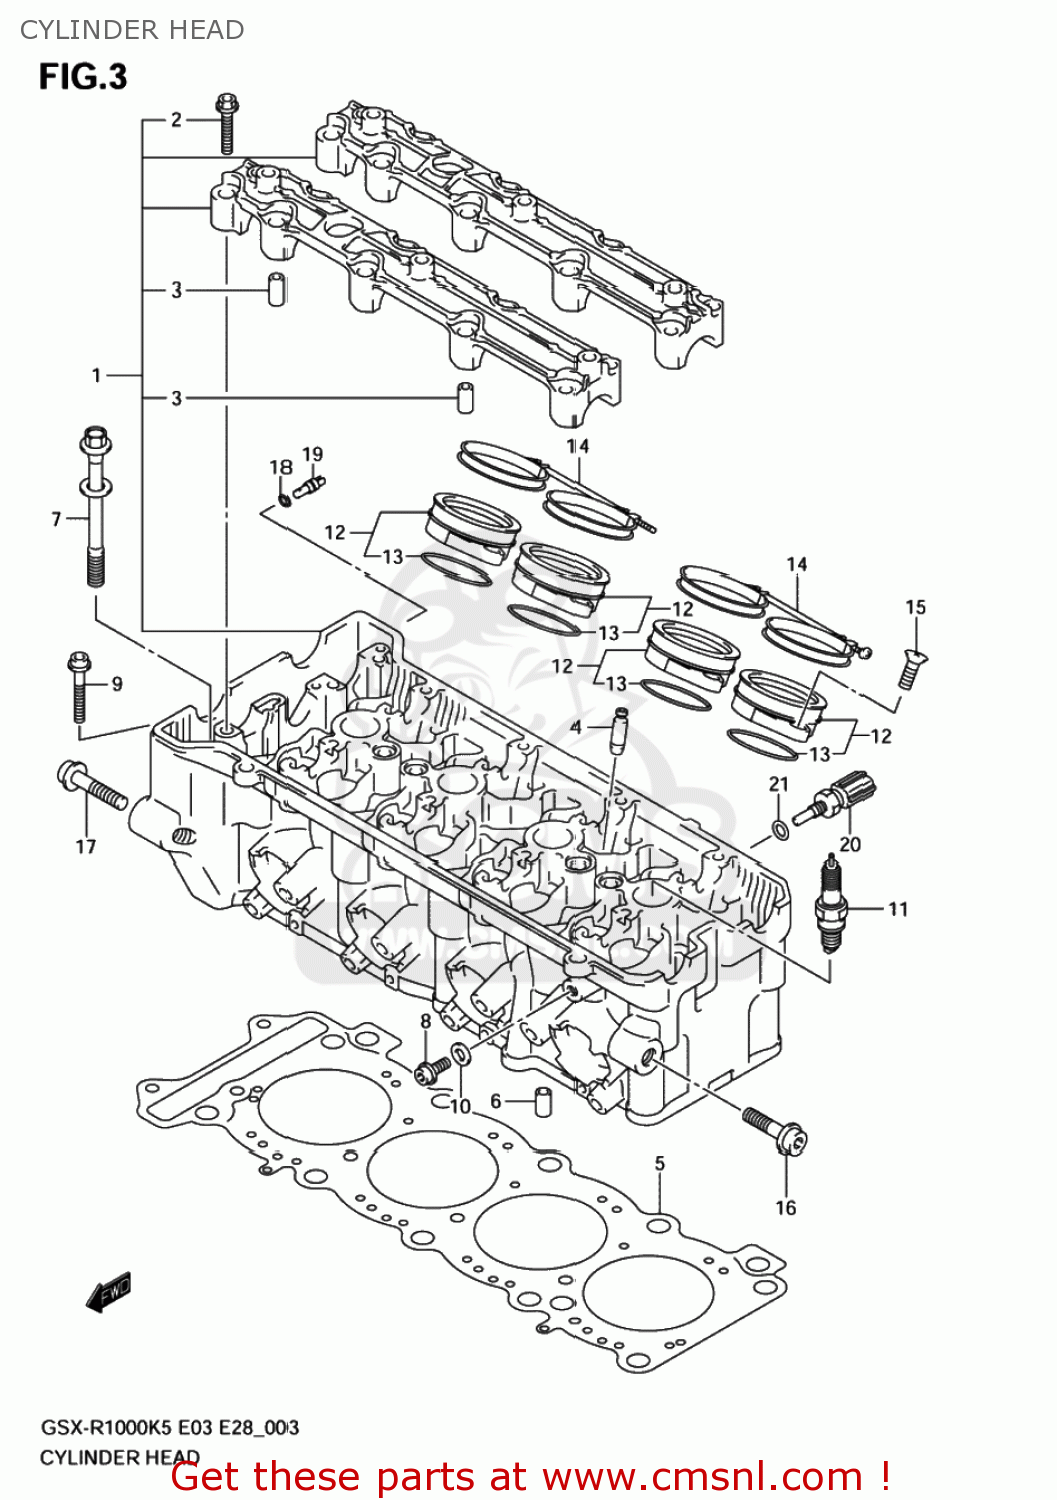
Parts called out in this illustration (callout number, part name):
1	HEAD ASSY,CYLINDER
2	BOLT(6X40)
3	PIN(6.2X8X16)
4	GUIDE,VALVE(OS:0.3)
5	GASKET,CYLINDER HEAD (NAS)
6	PIN
7	BOLT,CYLINDER HEAD(L:105)
8	BOLT(6X12)
9	BOLT,CYL.OIL P
10	GASKET(5.8X13X1.2) (NAS)
11	PLUG,SPARK(CR8E)
12	PIPE ASSY,INTAKE
13	O RING(D:2.4,ID:47.2)
14	CLAMP,INTAKE PIPE
15	SCREW ,6X16
16	BOLT(10X45)
17	BOLT(10X55)
18	O RING(D:1.2,ID:4)
19	JET(8)
20	SENSOR,WATER TEMP
21	GASKET(12X17X1) (NAS)
